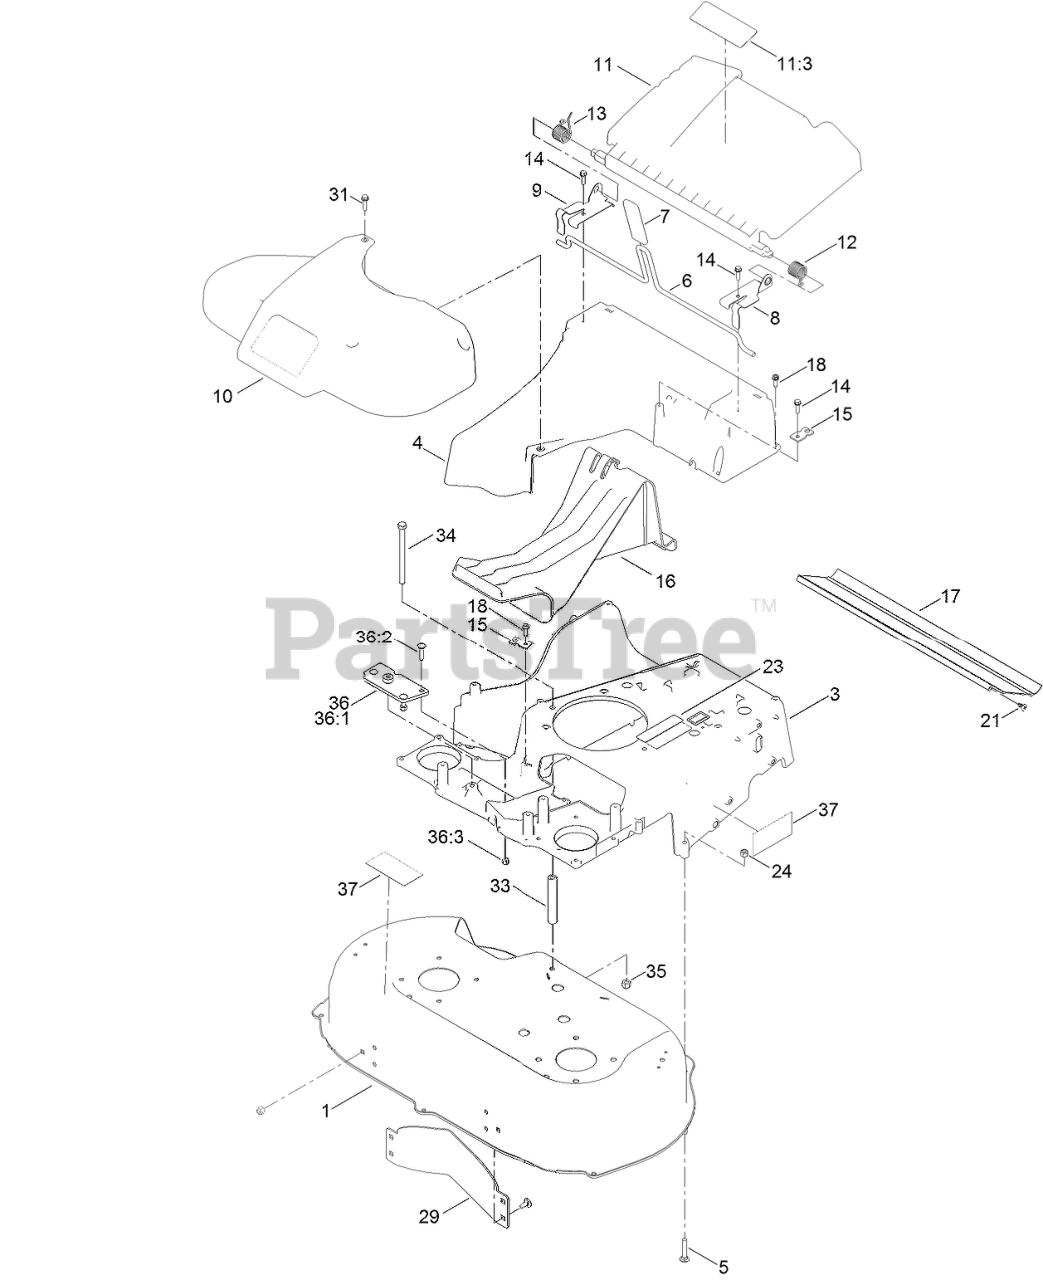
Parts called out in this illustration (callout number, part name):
1	HOUSING ASM
3	FRAME
5	BOLT-CAR
6	ROD-RELEASE, HANDLE
7	GRIP-LEVER
8	BRACKET-DOOR, LH
9	BRACKET-DOOR, RH
10	BELT COVER ASM
11	REAR DEFLECTOR ASM
11:3	DECAL-WARNING
12	SPRING-TORSION
13	SPRING-TORSION
14	SCREW-HWH
15	BRACKET-CABLE, TRACTION
16	PLUG-MULCH
17	SHIELD-TRAILING
18	SCREW-HWHTF
21	SCREW-PTH
23	DECAL-ARRESTOR, SPARK
24	NUT-LOCK, NI
29	BAFFLE-CONTROL
31	SCREW-HWHTF
33	SPACER-SHIELD
34	SCREW-HH
35	NUT-HEX
36	FRAME PLATE KIT
36:1	PLATE-FRAME
36:2	SCREW-CARR
36:3	NUT-LOCK, NI
37	DECAL-TOOL, THD
